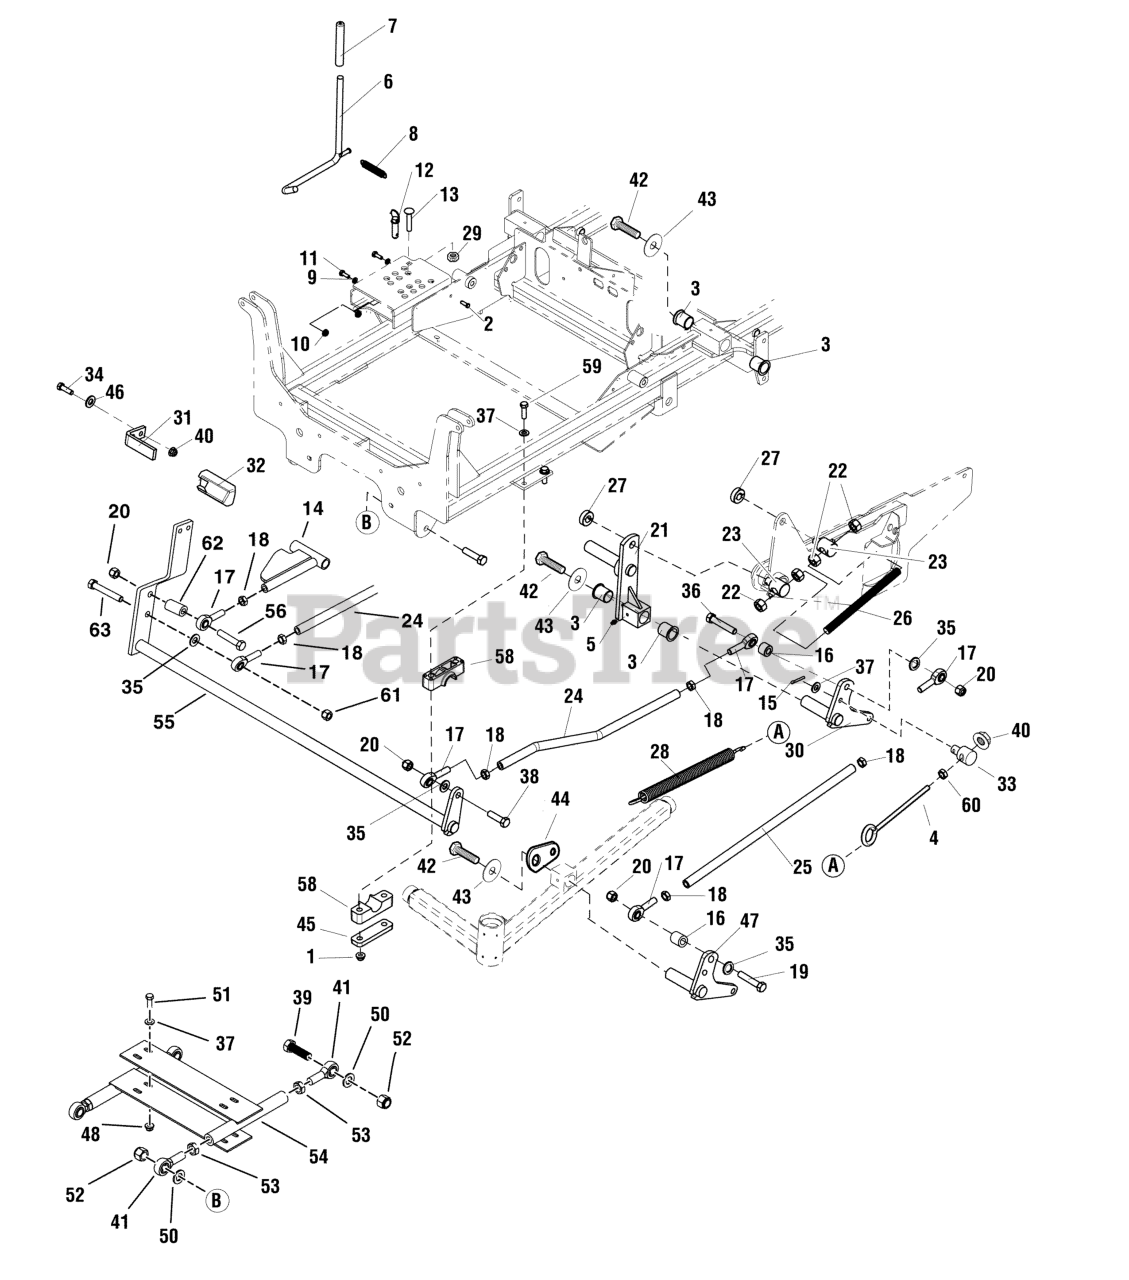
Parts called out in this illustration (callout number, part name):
1	NUT, 3/8-16 HEX NYLOCK FLANGE
2	PIN, CLEVIS, 1/4 X 7/8, PLATED
3	BUSHING, 1.00 X 1.13 X 1.38, PLASTIC
4	EYEBOLT, 3/2-16 X 8", 1" EYE
5	GREASE FITTING, 1/4-28 STRAIGHT
6	WELD, ROD DECK LIFT - BLK
7	GRIP, FOAM
8	SPRING, EXTENSION
9	WASHER, 1/4 SAE
10	NUT, 1/4-20 HEX SERR. FLANGE
11	BOLT, 1/4-20 X 3/4" GD5 YZ
12	PIN, HITCH, 1/2 X 2.00 OAL, YP
13	BOLT, 3/8-16 X 2", CARRIAGE
14	WELD, DECK ADJUST LINK - RED
15	PIN, COTTER, 1/8" X 3/4
16	SPACER, .52 X 1.00 X .75
17	BALL JOINT, 1/2-20, MALE
18	NUT, 1/2-20 HEX JAM
19	BOLT, 1/2-13 X 2-3/4 GD5 CZ
20	NUT, 1/2-13 HEX NYLON LOCK
22	NUT, 5/8-11 HEX
23	PIVOT, SPRING ROD
24	ROD, DECK LIFT BENT
25	ROD, DECK LIFT, OUTER
26	ROD, 5/8-11 X 9.00
27	COLLAR, 5/8" SPLIT
28	SPRING, DECK LIFT ASSIST
29	NUT, 3/8-16 HEX SIDE LOCK
31	PEDAL, FOOT - BLK
32	PEDAL, Rubber
33	ADJUSTER, DECK HANGER
34	BOLT, 3/8-16 X 1-1/4" GD5 CZ
35	WASHER, 1/2" SAE
36	BOLT, 1/2-13 X 3-1/2, HEX HD, GD5, CZ (SV)
37	WASHER, 3/8 SAE
38	BOLT, 1/2-13 X 1-3/4 GD5 CZ
39	BOLT, 3/4-16 X 2-1/2 YZ GD5
40	NUT, 3/8-16 HEX NYLON LOCK
41	BALL JOINT, 3/4-16, MALE
42	WASHER, .390 X 1.50 X .109, YZ
43	BOLT, 3/8-16 X 3/4, PLT W/PATCH
44	MOUNT, SPRING DECK LIFT - RED
45	PLATE, PIVOT BLOCK SUPPORT - BLK
46	WASHER, 3/8" GR9 FLAT
47	WELD, PIVOT DECK LIFT - LH - RED
48	NUT, 3/8-16 HEX SERRATED FLANGE
49	WELD, DECK LIFT SHAFT - RED
50	WASHER, 3/4 SAE
51	BOLT, 3/8-16 X 1" GD5 CZ
52	NUT, 3/4-16 HEX NYLON LOCK
53	NUT, 3/4-16 HEX JAM
54	WELD, DECK STABILIZER - BLK
55	WELD, DECK LIFT SHAFT - RED
56	BOLT, 1/2-13 X 4" GD5 CZ
57	WELD, PIVOT DECK LIFT - RH - RED
58	PIVOT BLOCK, PLASTIC
59	BOLT, 3/8-16 X 2-3/4" GD5 CZ
60	NUT, 3/8-16 HEX
61	NUT, 1/2-13 HEX SIDE LOCK
62	SPACER, .52 X 1.00 X 1.75
63	BOLT, 1/2-13 X 2" GD5 CZ
